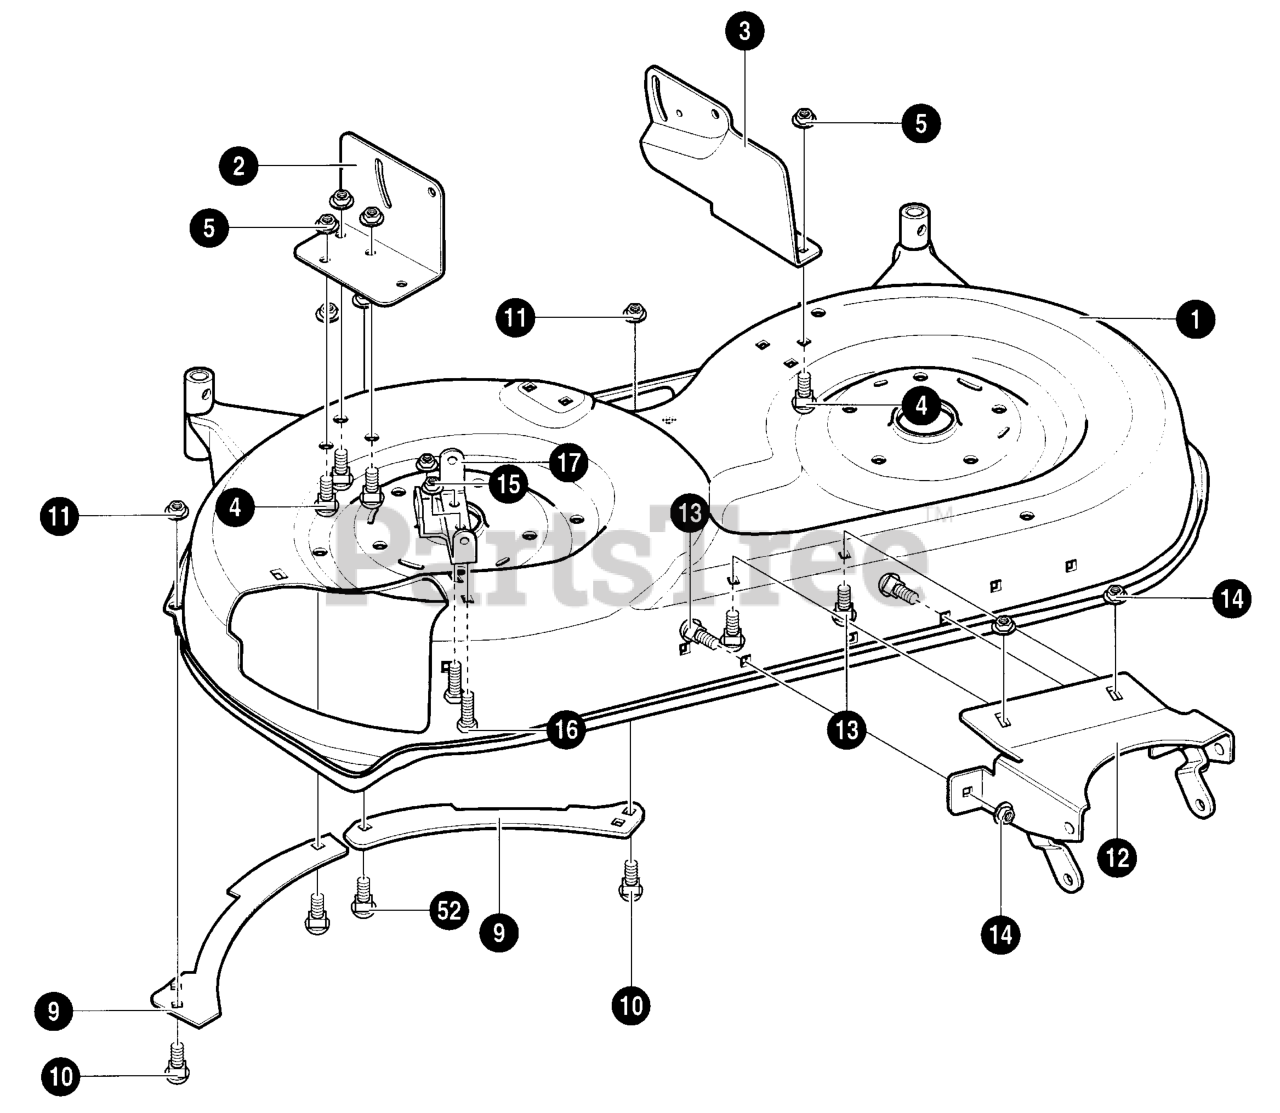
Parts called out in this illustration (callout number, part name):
1	ASSY BLD HSING 42"
2	BRACKET, DECK RH
3	BRACKET, DECK LH
4	BOLT, 5/16-18X.63
5	NUT, 5/16-18
9	TOEGUARD, FLANGE
10	BOLT, 5/16-18X.63
11	NUT, 5/16-18
12	ASSY FRONT BRACKET ROLLER
13	BOLT, 5/16-18X.63
14	NUT, 5/16-18
15	BRACKET, CHUTE
16	BOLT, 5/16-18X.63
17	NUT, 5/16-18
